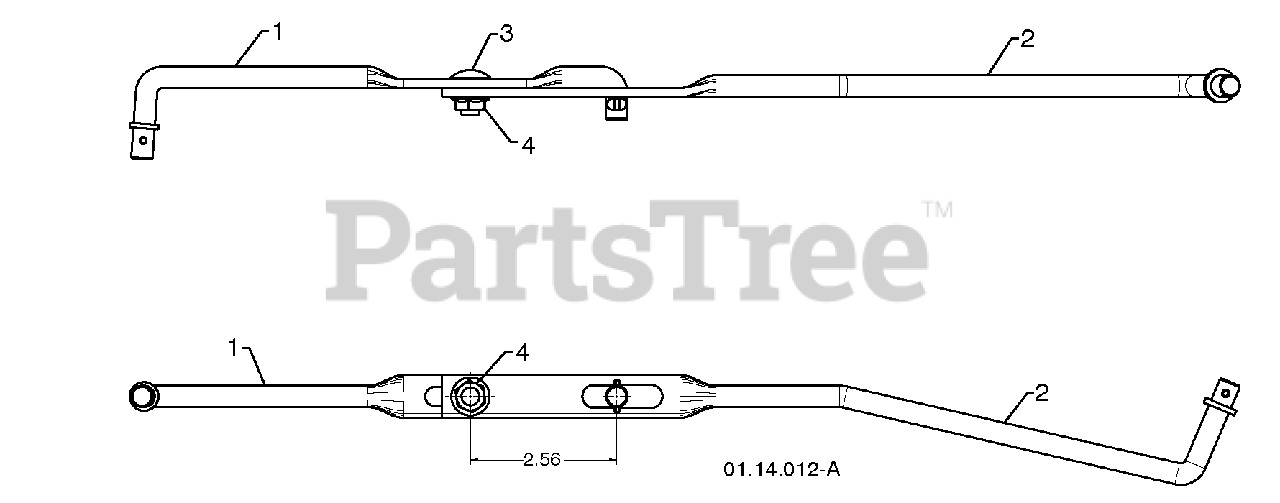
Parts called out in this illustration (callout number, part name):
1	SHIFTER ROD TOP
2	SHIFTER ROD BOTTOM
3	CARRIAGE BOLT 5/16-18 X .75
4	NUT 5/16-18
